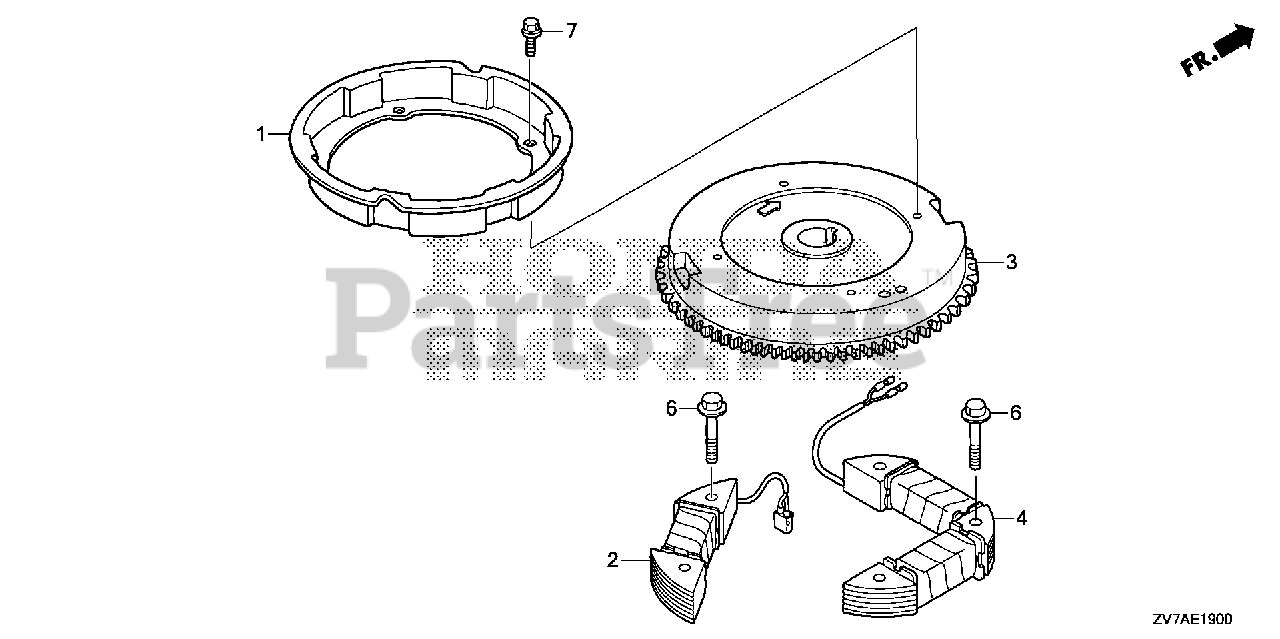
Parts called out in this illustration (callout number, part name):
1	PULLEY, STARTER
2	COIL ASSY., POWER
3	FLYWHEEL *TBLACK* (BLACK)
4	COIL ASSY., CHARGE (12V-10A)
6	BOLT, FLANGE (6X35) (CT200)
7	BOLT, FLANGE (6X12)
